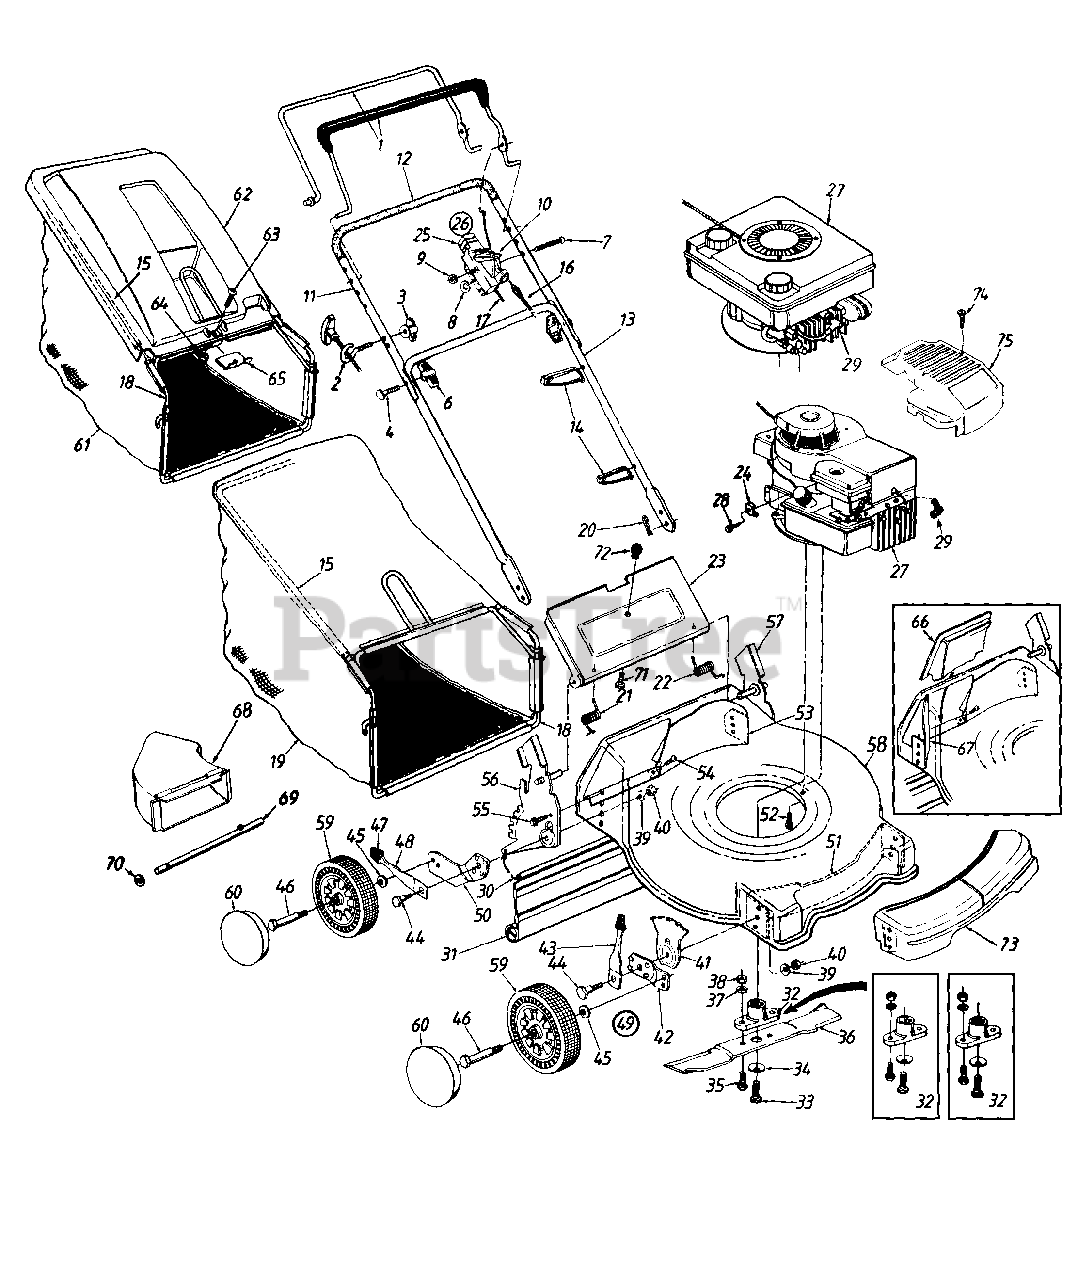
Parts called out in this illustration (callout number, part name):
2	Rope Guide
3	Handle Knob 1/4-20 Thd.
4	Curved Hd. Bolt 5/16-18 x 2" Lg.
6	Hand Knob
7	Oval C-Sunk Mach. Scr.
8	Spr. Wash. .66" I.D.
9	Hex L-Nut 1/4-20 Thd.
10	Throttle Lever
14	Cable Tie
16	Control Cable - 39"
17	Throttle Control Wire - 51"
20	Int. Cotter Pin 5/16" Dia.
21	Door Spring - R.H.
22	Door Spring - L.H.
25	Throttle Body
27	Engine
28	Hex Wash. Hd. Scr. #10-32 x .62" Lg. (B&S)
29	Spark Plug Boot
30	Wire Rod
31	Rear Flap
32	Blade Adapter Kit (Keyed)
33	Hex Bolt 3/8-24 x 1.5" Lg.
34	Bell-Wash..39" I.D.
35	Hex Bolt 3/8-24 x 1" Lg.
36	21" Blade
37	L-Wash. 3/8" I.D.
38	Hex Nut 3/8-24 Thd.
39	Bell-Wash..39" I.D. x 1.38"
40	Hex Nut 3/8-1 6 Thd.
41	Height Adj. Plate
43	Spring Lever Ass'y. w/Knob
44	Shld. Bolt .5" Dia. x .357"
45	Bell-Wash. .38" I.D. x .88" O.D.
46	Axle Bolt
47	Spring Lever Knob
48	Spring Lever
49	Height Adj. Ass'y. Comp.- R.H.
50	Pivot Bar
54	Torx Mach. AB-Tap Ser. 1/4 x .62" Lg.
55	Hex L-Wash. Hd. AB-Tap Scr. 1/4 x .62" Lg.
60	Hub Cap
61	Grass Bag
62	Hard Top Cover
63	Pan Hd. Mach. Scr. 1/4-20 x .5" Lg.
64	Hex Nylon L-Nut 1/4-20 Thd.
68	Deflector
69	Rod
70	Push Speed Nut
71	Truss Scr. #10-24 x .38" Lg.
74	Hi-Lo Scr. #10 x 1.25" Lg.
75	XTE Black Shroud
